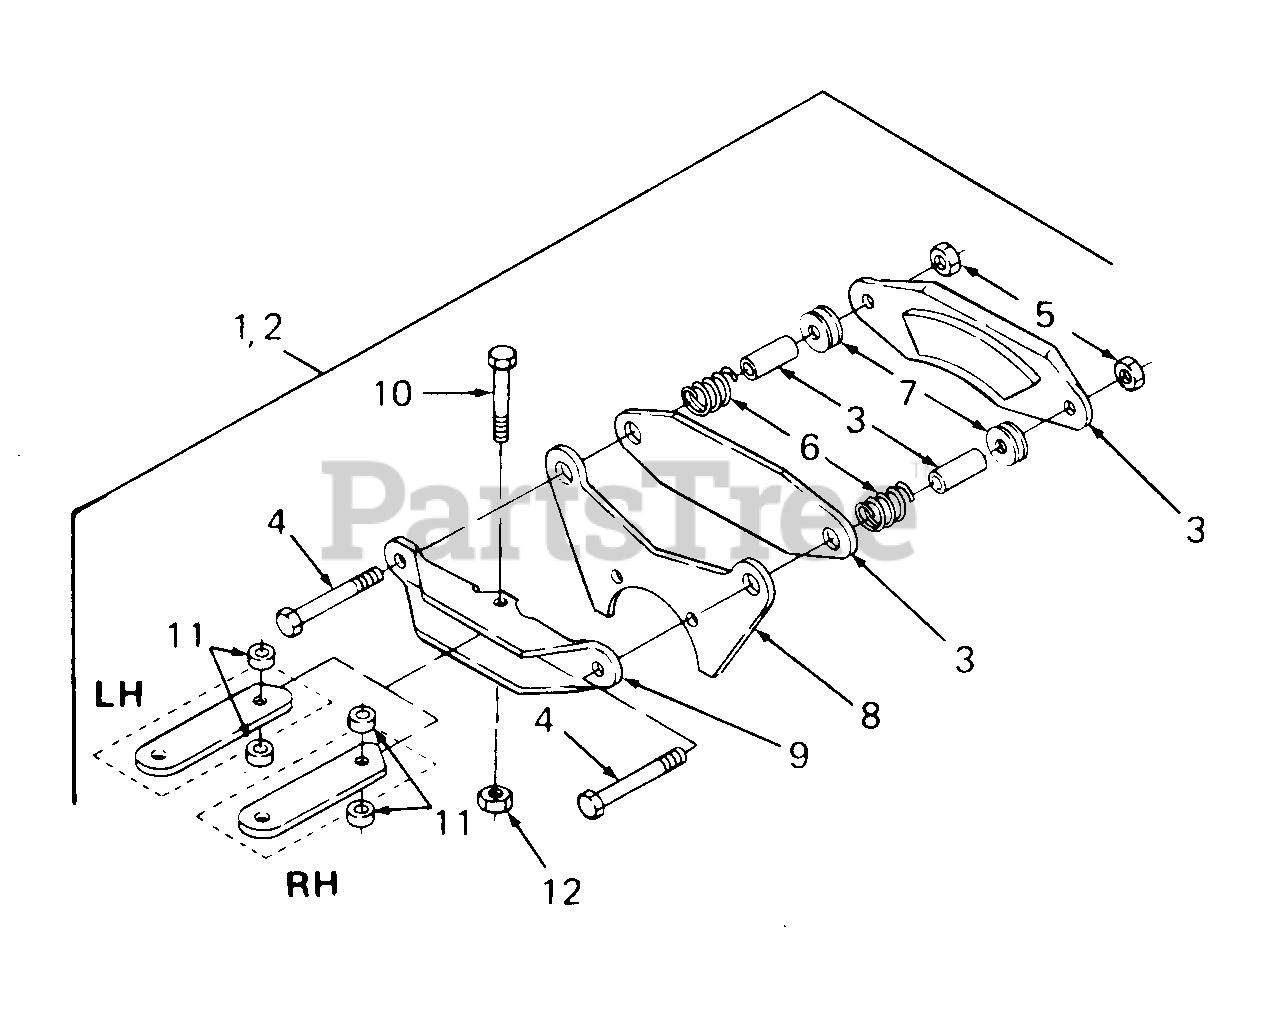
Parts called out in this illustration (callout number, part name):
1	Brake Kit, RH Caliper
2	Brake Kit, LH Caliper
3	Puck Kit, Brake
4	Screw, Hex Cap, 3/8-24 X 2.50 Lg GR5
5	Nut, Hex Lock, 3/8-24 GR5
6	Spring, Compression
7	Washer, Flat, .390 X 1.0 X .030 Thk HDN
8	Bracket, Brake Mounting
9	Bracket Assy, Actuator
10	Screw, Shoulder
12	Nut, Hex Top Lock, 1/4-20
